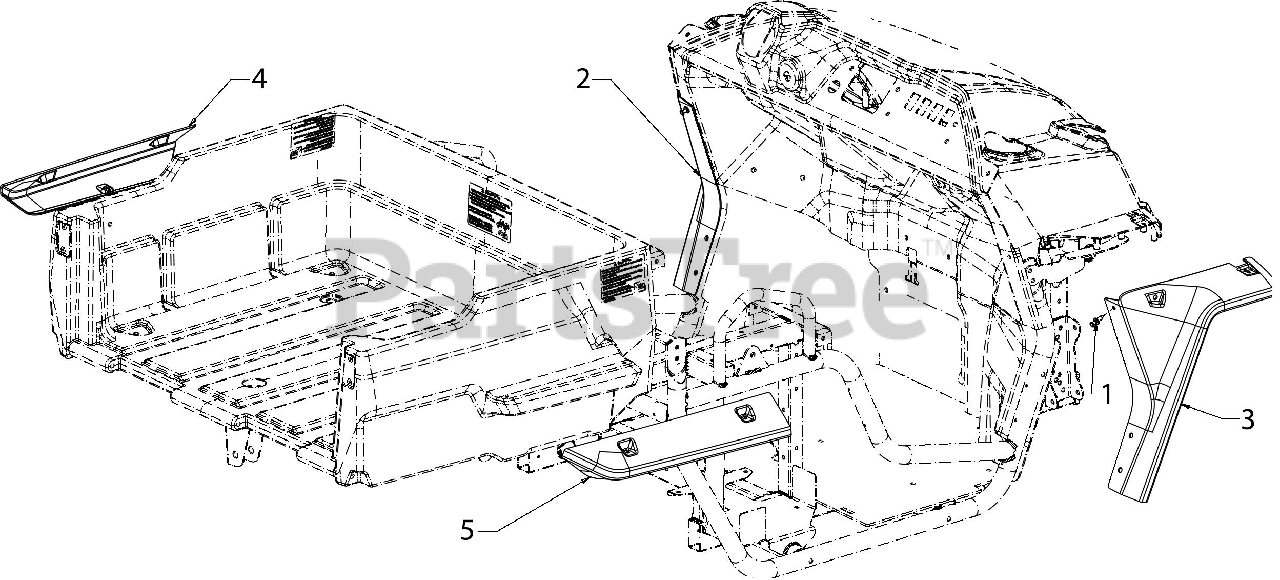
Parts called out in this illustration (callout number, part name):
1	PLASTIC RIVET
2	FRONT FENDER (LH)(BLUE)
3	FRONT FENDER (RH)(BLUE)
4	REAR FENDER (LH)(BLUE)
5	REAR FENDER (RH)(BLUE)
